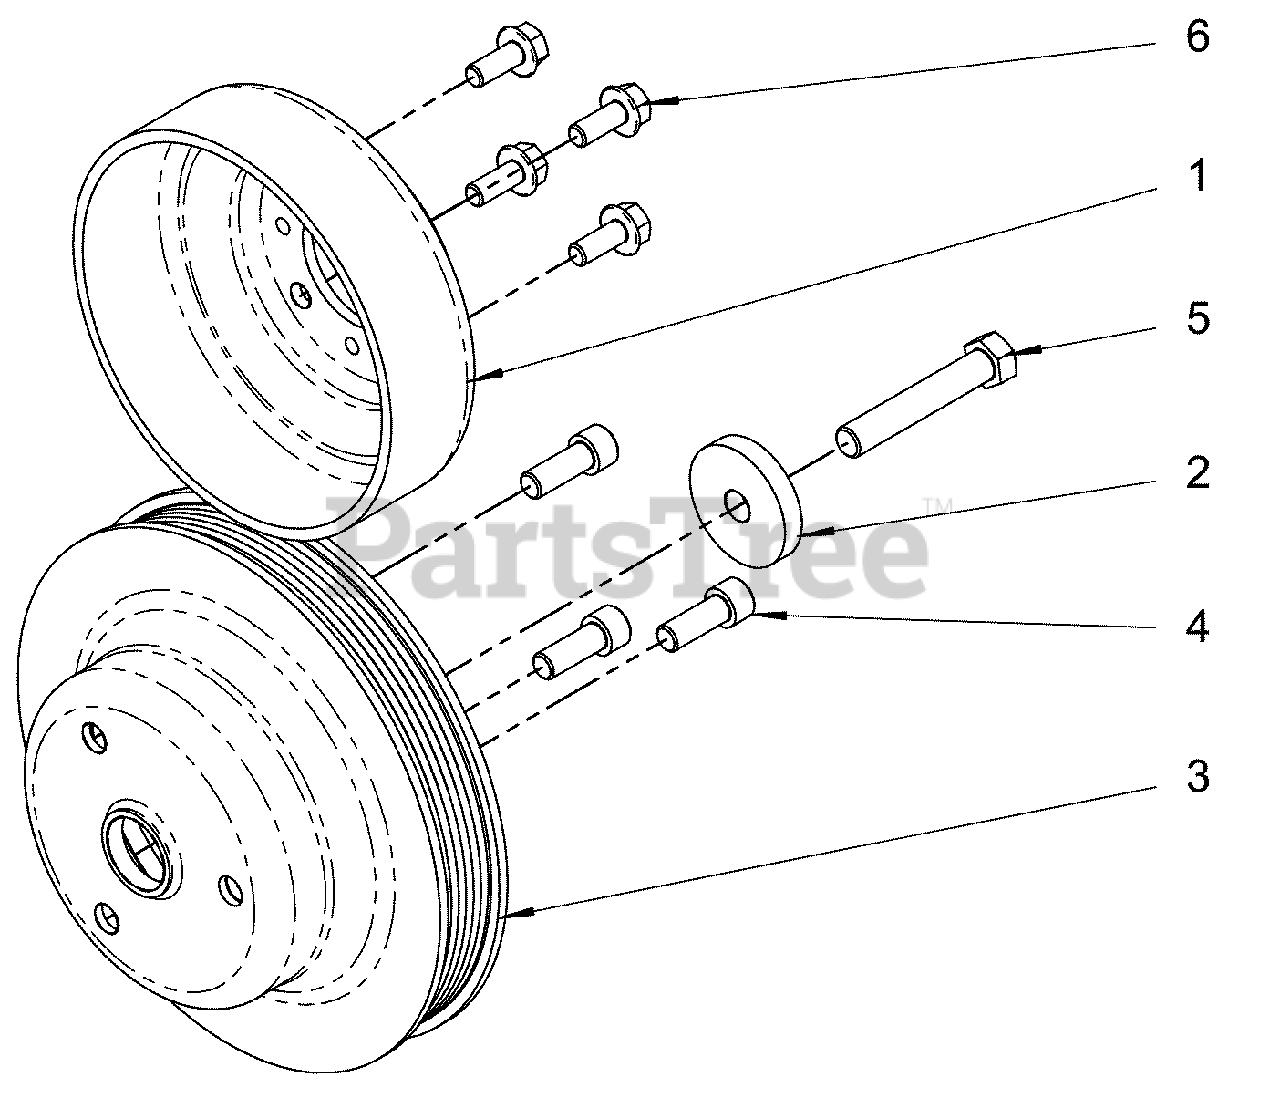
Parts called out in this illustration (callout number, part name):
2	* WASHER
4	* BOLT
5	* BOLT
6	* BOLT
